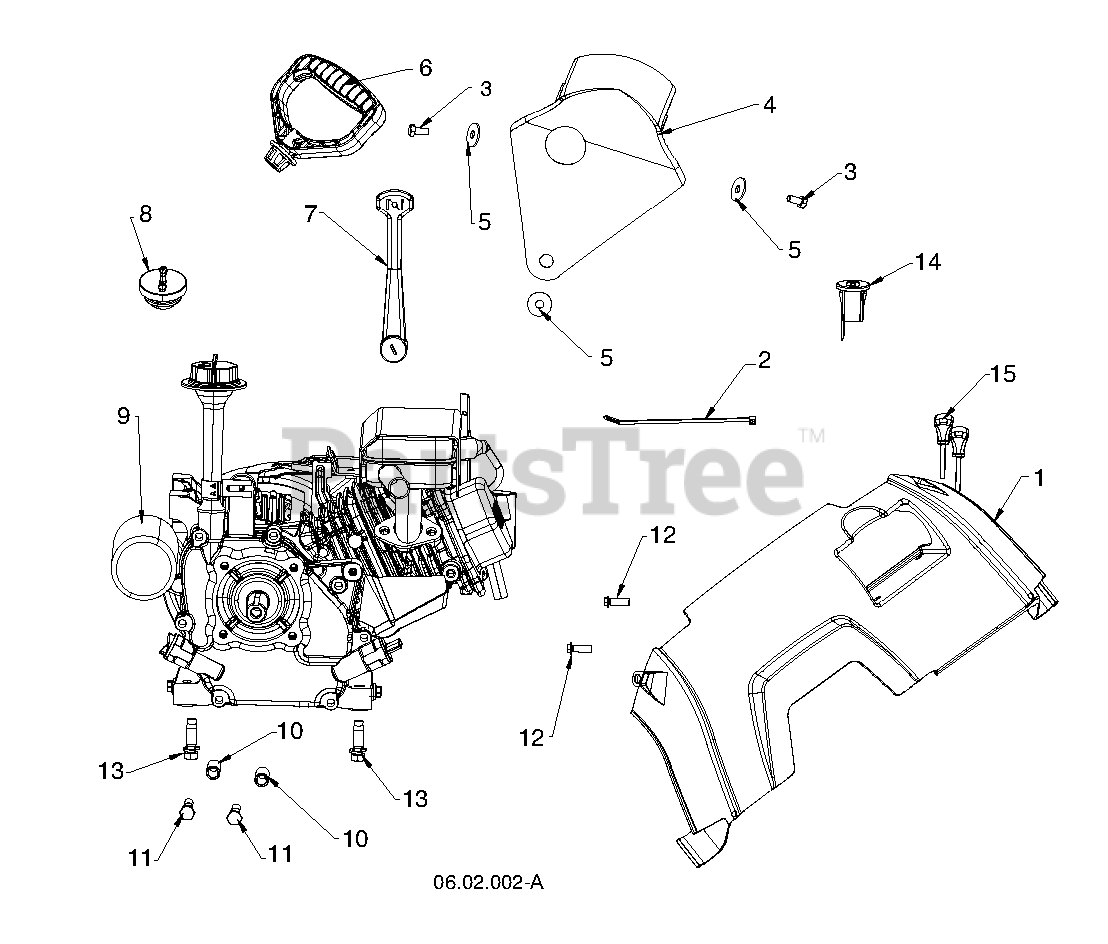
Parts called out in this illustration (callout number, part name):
1	COVER REAR.LOWER.SSST.BLACK
2	WIRE.TIE
3	SCREW M6-1.0 X 14MM HEX (2 2MC
4	COVER.MUFFLER.136CC/208CC.LCT
5	Washer 9/32 x 7/8 x 16 Gauge (AYP part number)
6	RP HANDLE.STARTER
7	LEVER.CHOKE
8	RP BULB.PRIMER
9	ENGINE LCT.136CC.SNOW. 4 PARTS
10	SPACER.ENGINE
11	SCREW. 5/16-24 X 2.00"HHCS
12	SCREW.HX.13X.750
13	Hex Head Thread Rolling Screw 3/8-16 x 1-1/8 (AYP part number)
14	KEY HOUSING
15	KEY SET(2 KEYS) SKSN0407.1
